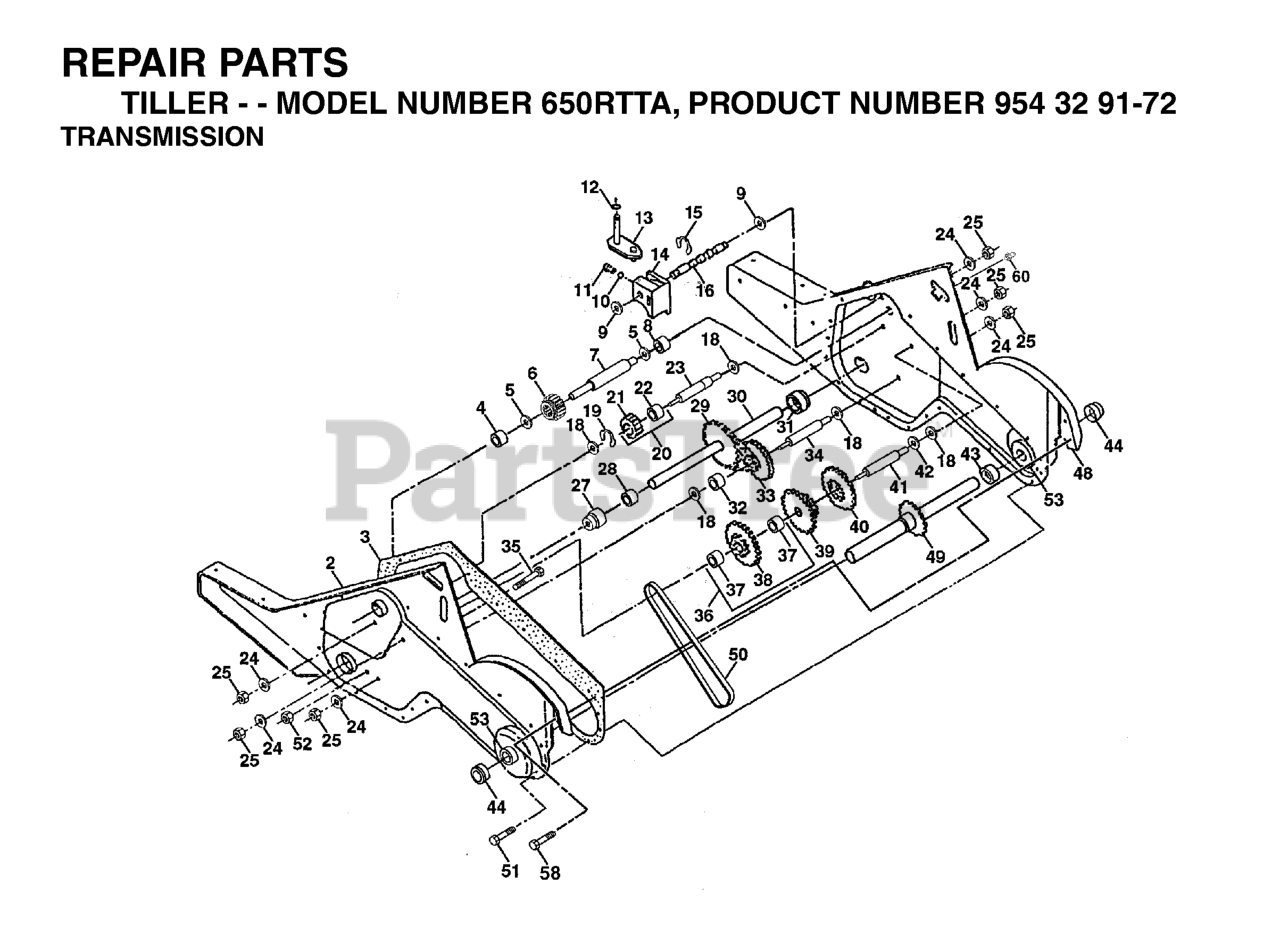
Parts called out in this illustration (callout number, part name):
1	TRANS SERV
2	GEAR CASE
3	GASKET
4	NEEDLE BRNG LT
5	THRUST WASHER
6	GEAR.PINION.INPUT
7	SHAFT.INPUT."D".TILLER
8	BEARING TI
9	WASHER, SEAL (2 2)
10	STEEL BALL KIT
11	SPRING-SHIFT CRT
13	BRACKET ASM.SHIFT.CRT
14	SHIFT FORK TI
16	SHAFT.SHIFTER.TILLER
20	GEAR ASSY CRT
21	GEAR-REV IDLR CRT
22	NEEDLE BEARING TI
24	LOCKWASHER
25	NUT.ASF.HEX.7/16
27	BEARING, SHAFT LH CRT
30	GROUND SHAFT ASS'Y
31	BEARING, SHAFT RH CRT
33	SPRCKT 8 GEAR CRT
34	SHAFT.SECONDARY.REDUCTION.CRT
35	SCRW WHIZ LOK CRT
36	SPROCKET.ASM.W/BEARING.TILLER
37	BEARING
38	SPROCKET, TINE
41	SHAFT.REDUCTION.TILLER
42	BRNG RACE T
44	SEAL ASM, OIL
48	GEARCASE, R.H. W/BEARING
49	TINE SHAFT
50	CHAIN.TILLER
51	SCREW
53	KIT.BEARING.TILLER.
58	BOLT SHOULDER 1/4-20 UNC X.875
60	ZERK M
